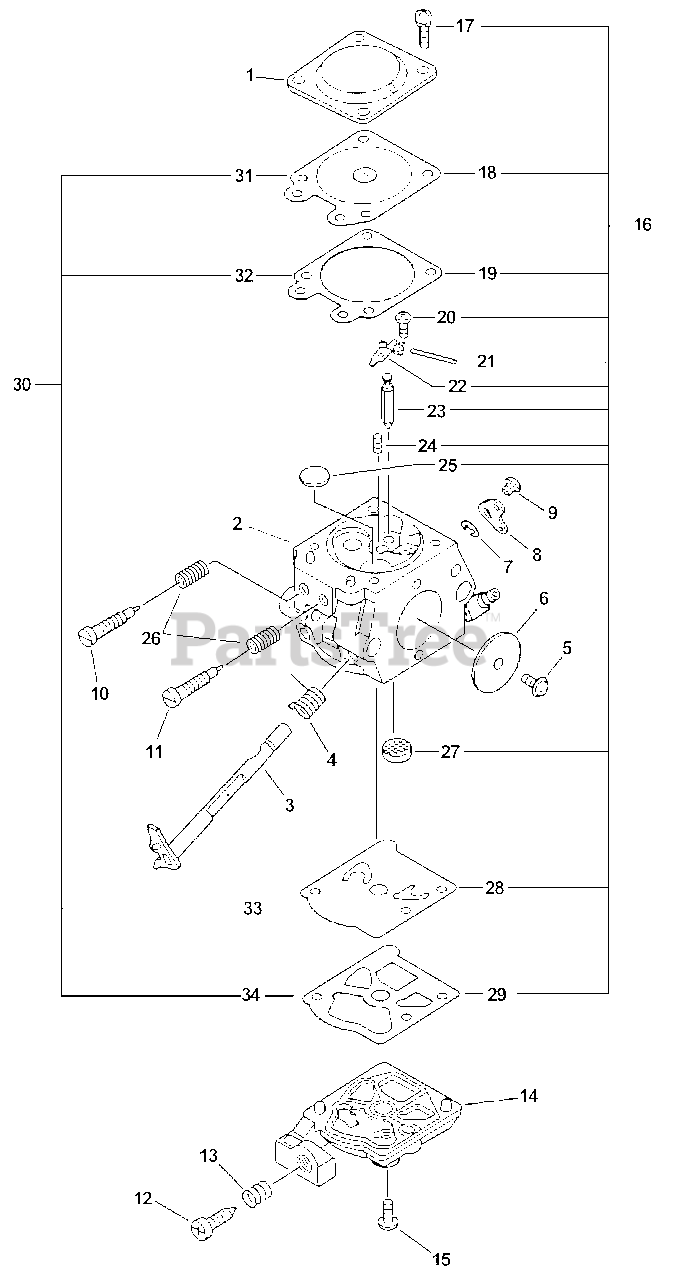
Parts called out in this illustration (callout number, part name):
1	COVER, METERING DIAPHRAGM
2	BODY, CARBURETOR
3	SHAFT, THROTTLE
4	SPRING, THROTTLE
6	VALVE, THROTTLE
8	LEVER, THROTTLE
9	LEVER, THROTTLE
10	NEEDLE, HIGH SPEED
11	NEEDLE, LOW SPEED
12	SCREW, IDLE ADJUST
13	SPRING, IDLE ADJUST
14	COVER, FUEL PUMP
16	REPAIR KIT, CARBURETOR
18	DIAPHRAGM, METERING
19	GASKET, DIAPHRAGM
20	SCREW, METERING LEVER PIN
21	PIN, METERING LEVER
22	LEVER, METERING
23	VALVE, INLET NEEDLE
24	SPRING, METERING LEVER
25	PLUG, WELCH
26	SPRING
27	STRAINER
28	DIAPHRAGM, PUMP
29	GASKET, PUMP
30	GASKET / DIAPHRAGM KIT
31	DIAPHRAGM, METERING
32	GASKET, DIAPHRAGM
33	DIAPHRAGM, PUMP
34	GASKET, PUMP
